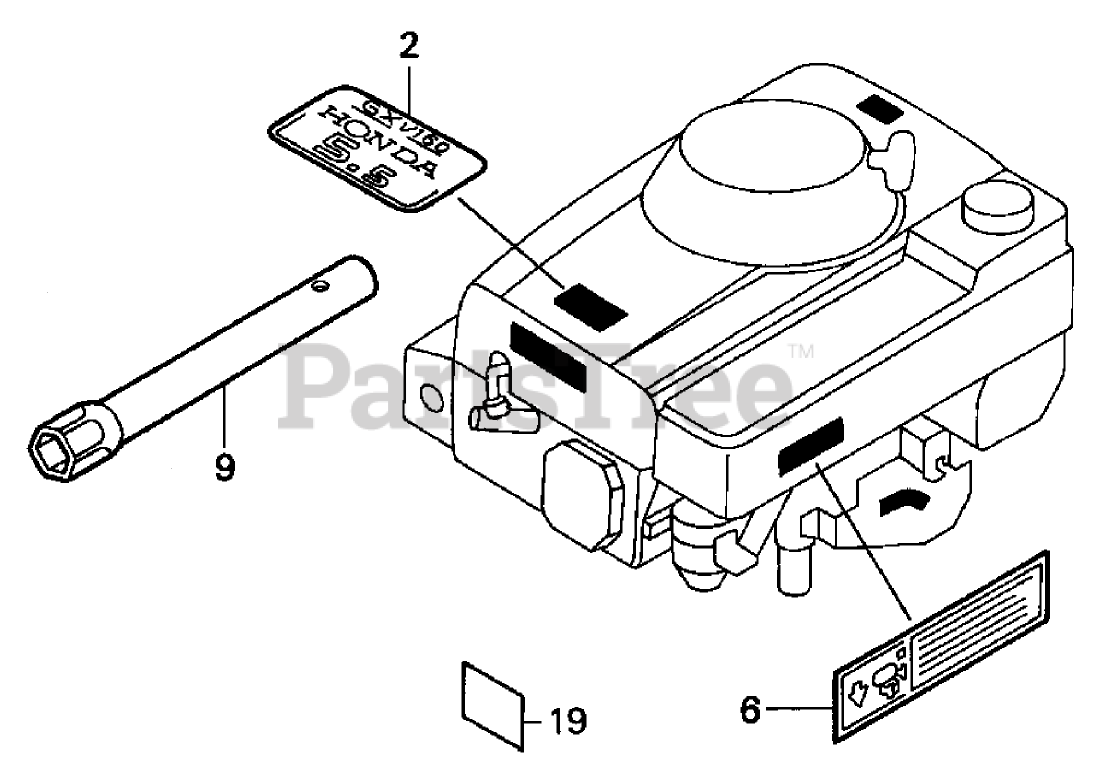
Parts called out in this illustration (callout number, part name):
2	MARK-EMBLEM (5.5 ES)
6	Mark, Honda
9	Wrench-Box (P21)
19	Mark, Type (A12)
